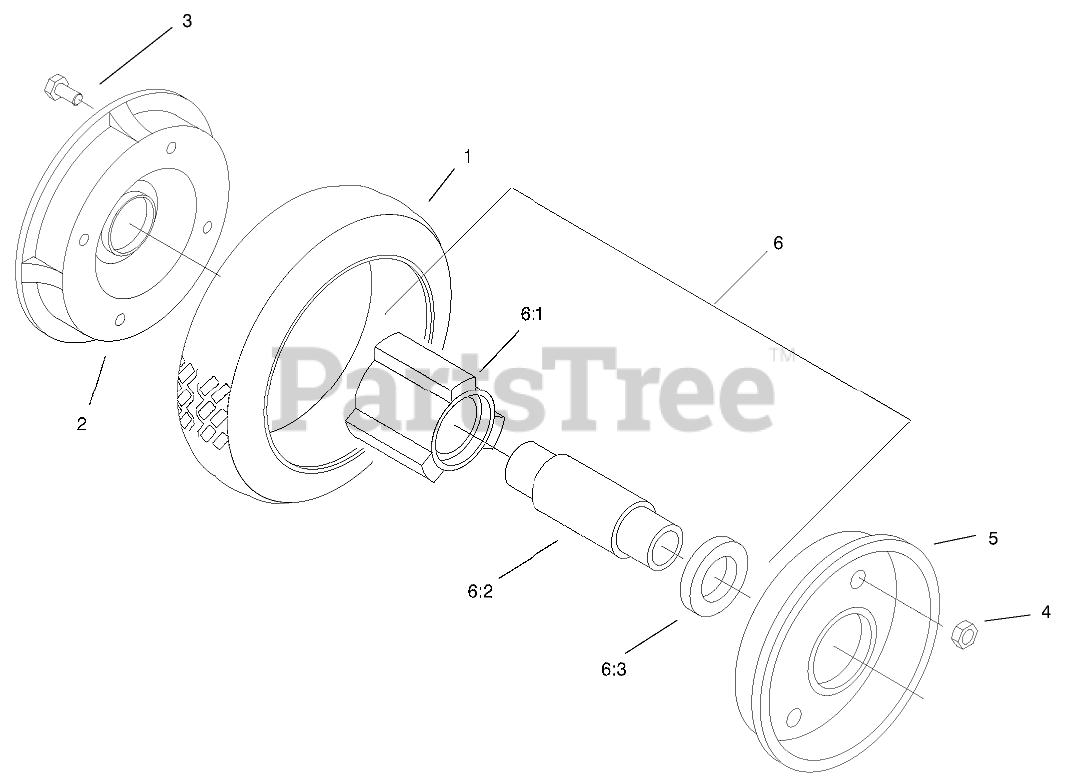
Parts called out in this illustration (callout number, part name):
2	PLATE-WHEEL, HALF
3	SCREW-HH
4	NUT-LOCK, NI
5	WHEEL HALF AND GEAR ASM
6	Hub & Brg ASM
6:1	HUB-BEARING
6:2	SPACER-BEARING
6:3	BEARING-WHEEL
